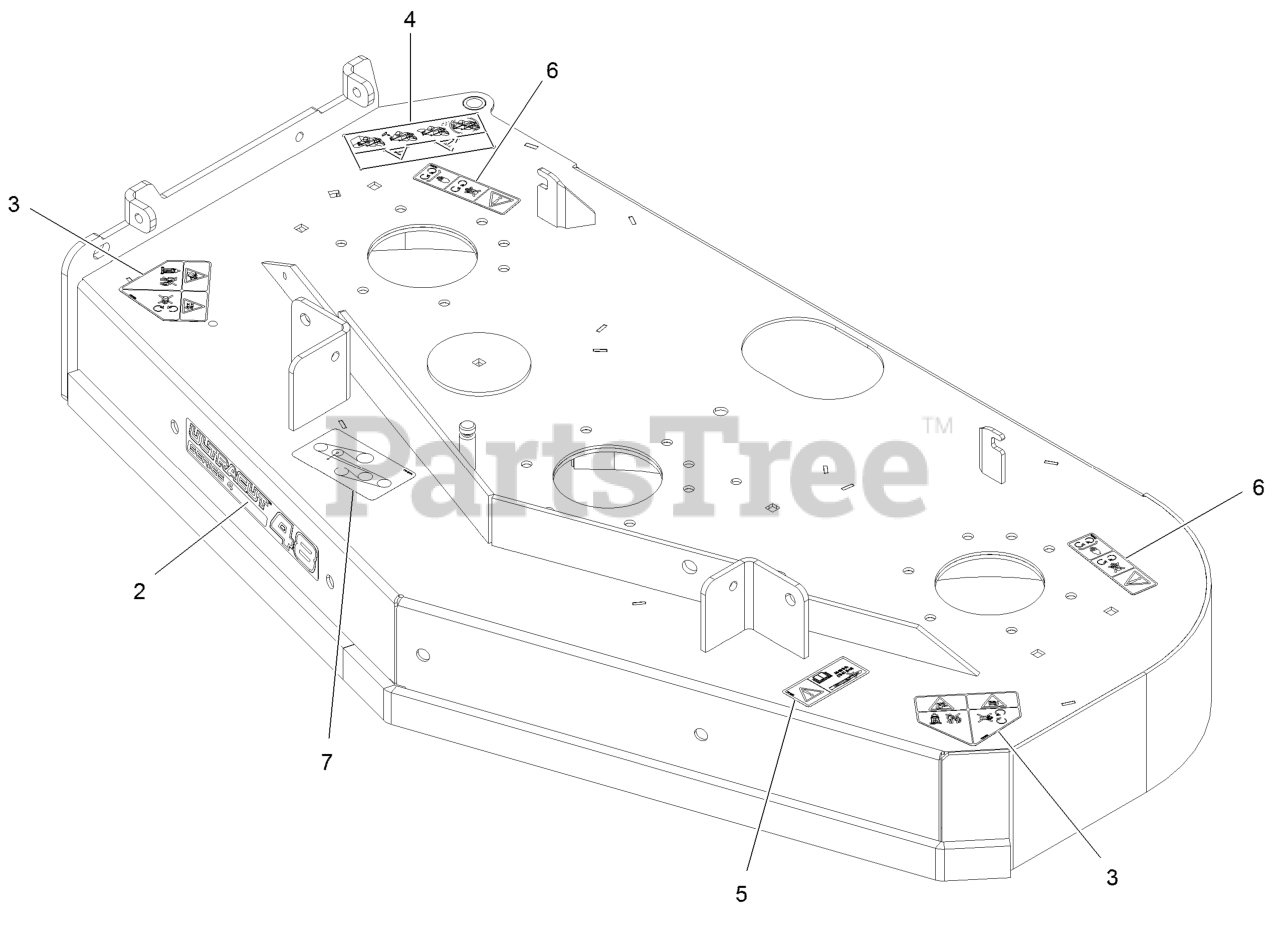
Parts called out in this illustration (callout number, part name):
2	Decal, 484
3	DECAL-DANGER
4	DECAL-WARNING, BAGGER
5	DECAL-BOLT TORQUE
6	DECAL-COVER, MISSING
7	DECAL-BELT ROUTING
